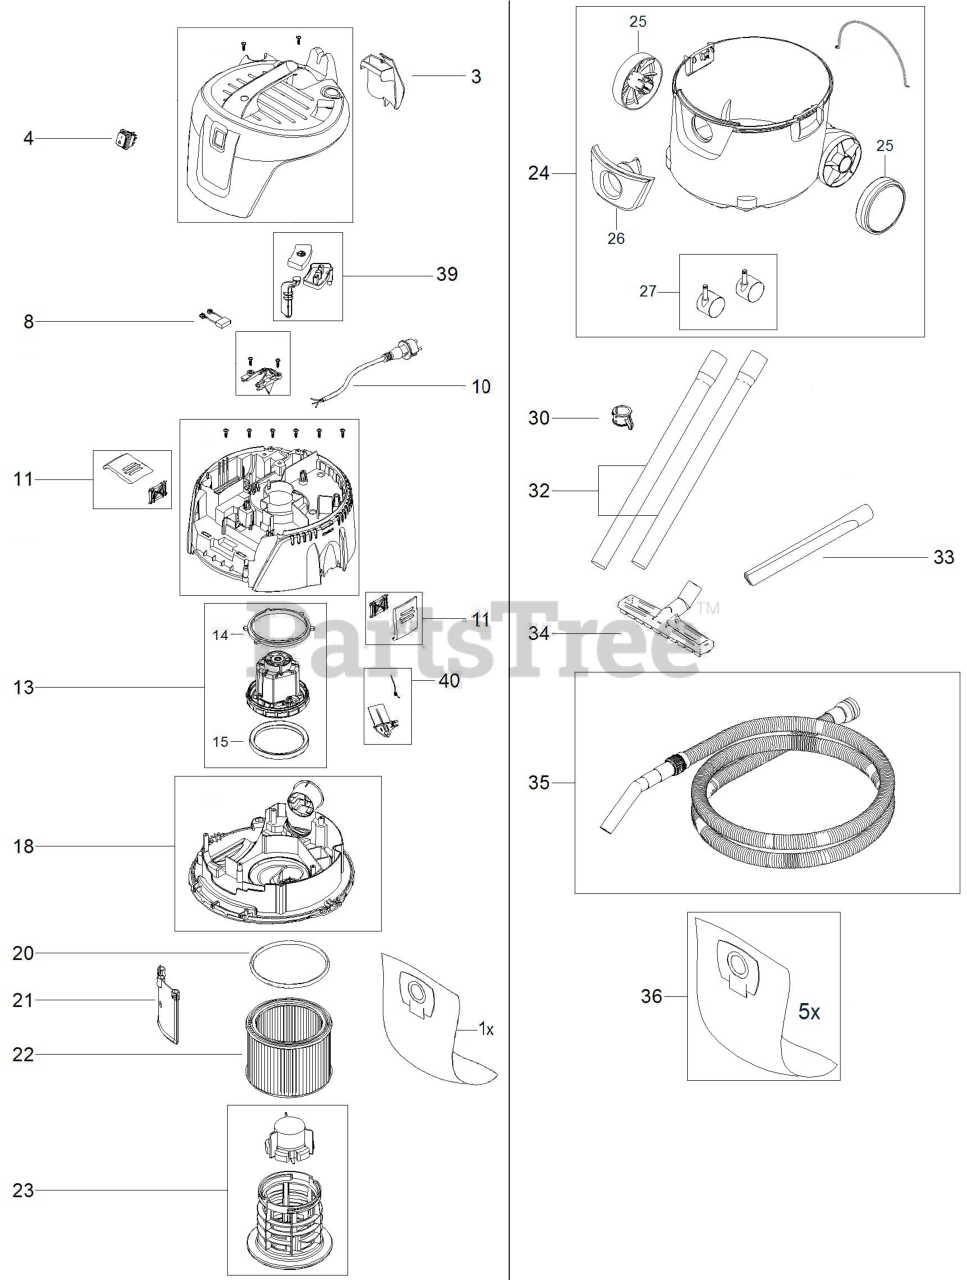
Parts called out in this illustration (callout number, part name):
1	HANDLE, UPPER GRAY
2	BAIL - SG, ORANGE
3	HANDLE, POSITION ADJ
4	HCS 5/16C X 3/4
5	WASHER, FRICTION
6	NUT 5/16C CENTERLOCK
7	RIVET.SNAP-MALE.HALF.NYLON.WHI
8	RIVET.SNAP-FEMALE.HALF.NYLON.W
10	BUSHING, STEP .34IDX1.82LG STL
11	HANDLE, WHEEL BRAKE
13	GRIP, PARK BRAKE
14	NUT 5/16 PUSH CAP
15	SWITCH, NC PLUNGER
16	TAPPED PLATE
17	WASHER - 3/16 LOCK ZD
18	SCR #10-24 X 3/4
19	THROTTLE CABLE, STUMP GRINDER
20	NUT 10-24 NYLOC
21	SWITCH, TOGGLE, STUMP GRINDER
22	BOOT, TOGGLE SWITCH
23	SPRING, EXTENSION
24	ROD ASM, PARK BRAKE
25	YOKE 5/16 ADJ CLEVIS
26	COMP. SPRING
27	WASHER 3/8 FLAT
28	CLEVIS PIN
29	HAIRPIN #2
30	ROD, POSITION ADJ
31	FLAT WASHER 5/16 SAE
32	RP_COTTER PIN 1/8 X 3/4
33	NUT 3/8C CENTERBLOCK
34	HCS 3/8C X 2
35	NUT 5/16F NYLOC
